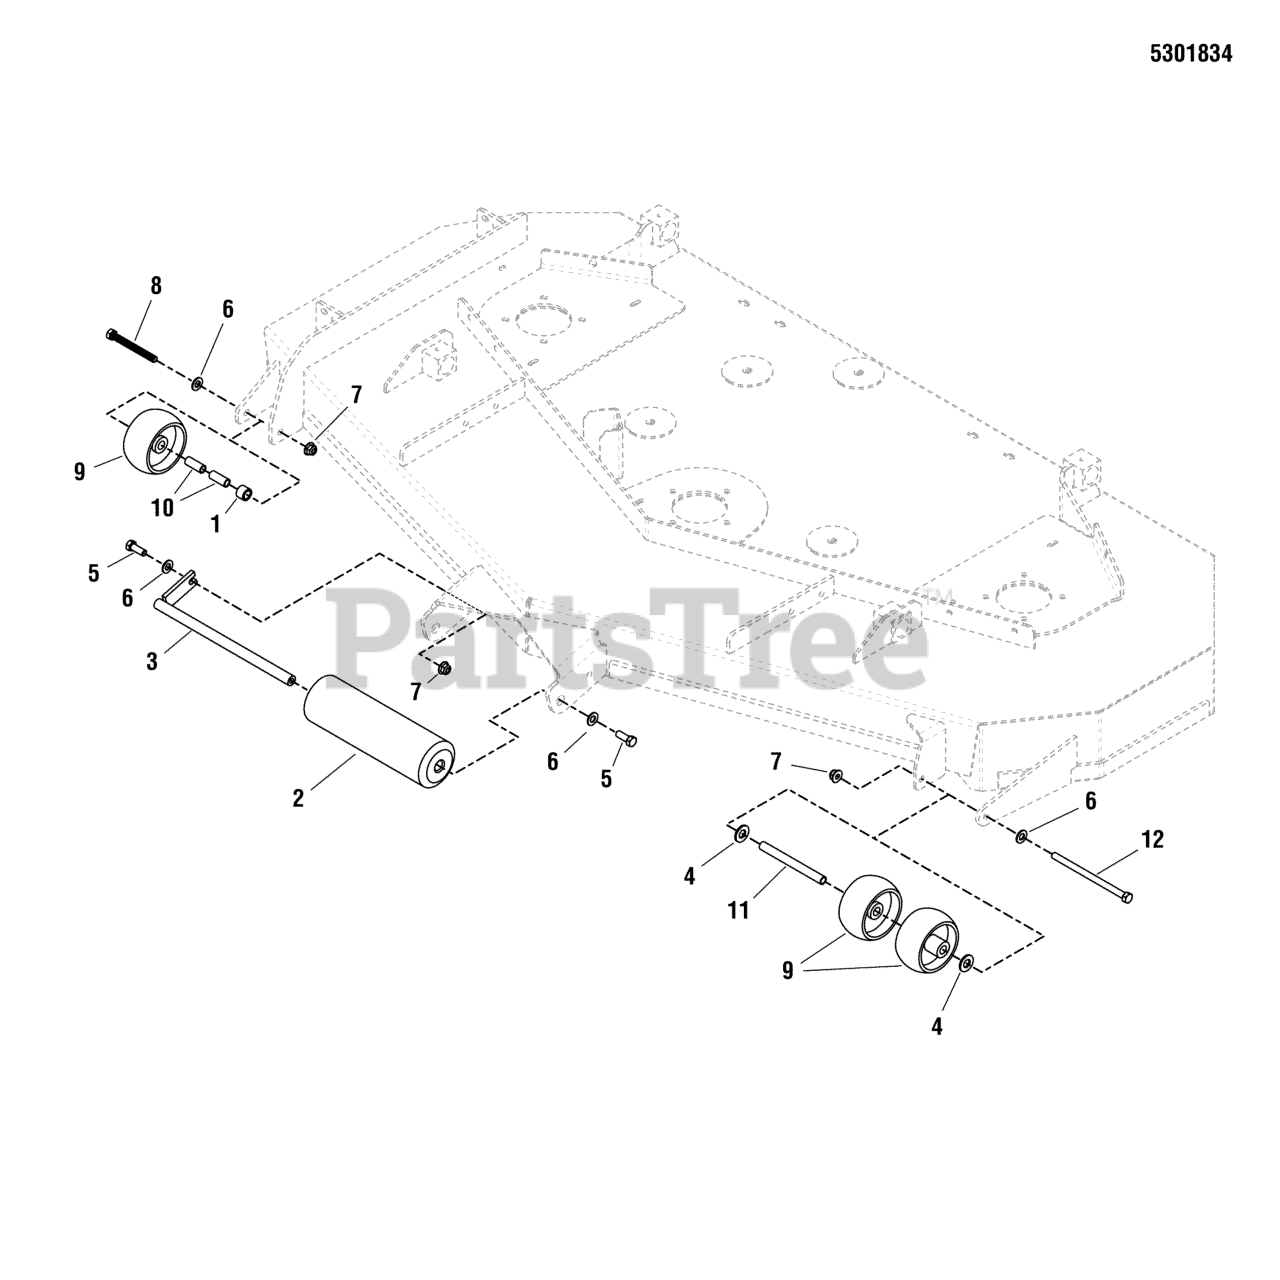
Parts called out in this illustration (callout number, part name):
1	SPACER, .51 X .75 X .56, PM, CZ
2	ROLLER, DECK
4	WASHER, 1/2" GD9 YZ
5	BOLT, 3/8-16 X 1" GD5 CZ
6	WASHER, 3/8 SAE
7	NUT, 3/8 - 16 HEX NYLOCK FLANGE
8	BOLT, 3/8-16 X 3-1/2" GD5 CZ
9	WHEEL- 2.00 WIDE 3.88 DIA 0.531ID POLY
10	SPACER, .38 X .50 X 1.25, CZ
11	SPACER, .38 X .50 X 5.06, CZ
12	BOLT, 3/8-16 X 6" GD5 CZ
